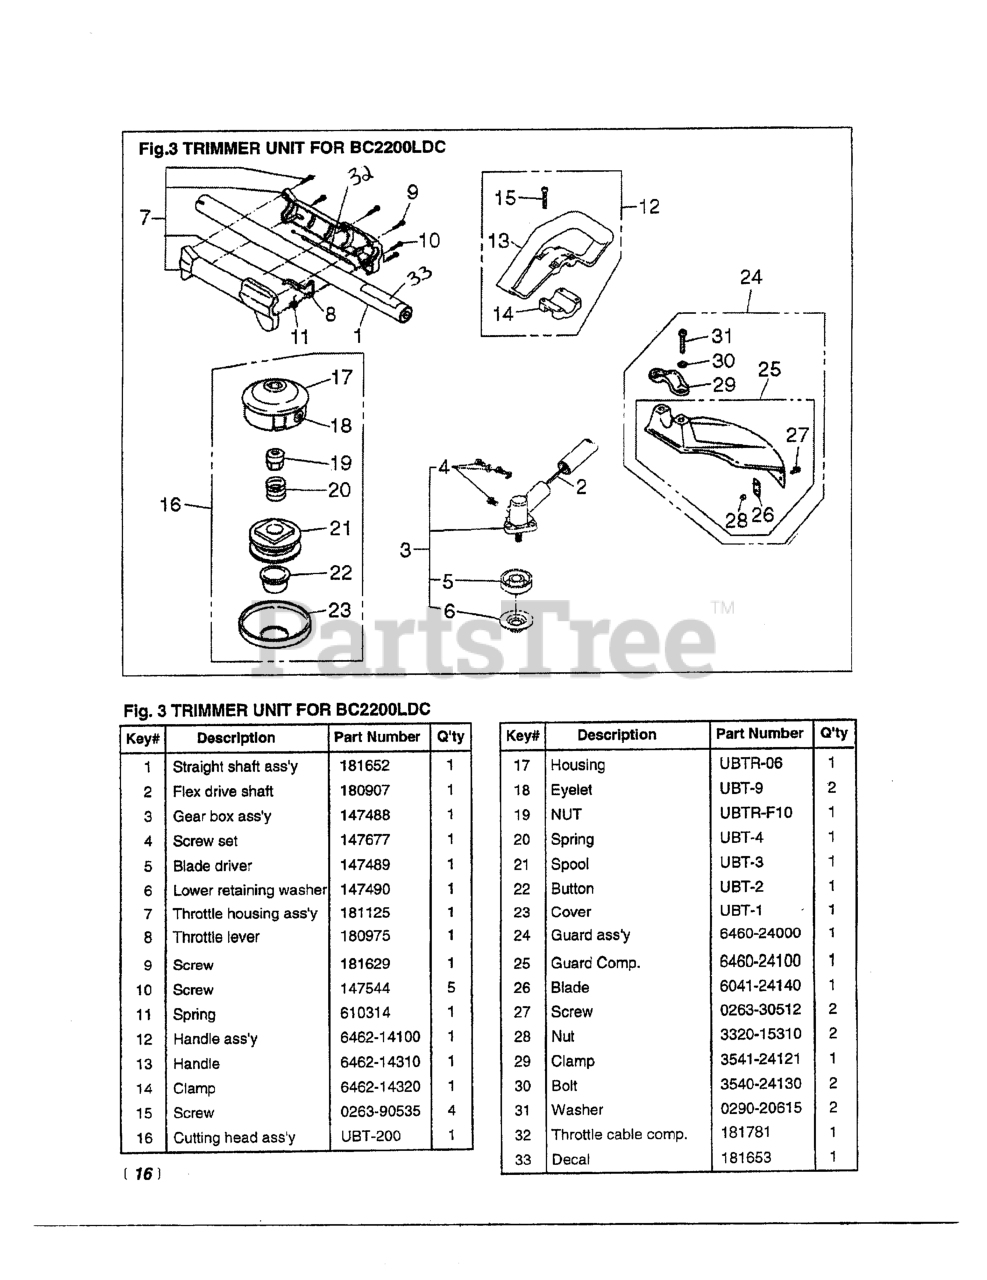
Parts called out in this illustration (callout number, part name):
1	DRIVE SHAFT HSG ASSY (SS)
2	SHAFT, FLEX (RLPS. 181773)
3	GEARCASE ASSEMBLY
4	HARDWARE, MOUNTING
5	HOLDER (U), BLADE DRIVER
6	HOLDER (L) (RPLS 613222)
8	LEVER, THROTTLE
9	SCREW, 8-32 X .437
11	SPRING, THROTTLE TRIGGER
12	HANDLE ASSEMBLY
13	HANDLE
14	CLAMP
15	SCREW, M5 x 35
16	CUTTING HEAD ASSY
17	HOUSING (ROUND) (NLA)
18	EYELET
19	BOLT (10MM ROUND FEMALE)
20	SPRING
21	SPOOL
22	BUTTON
23	COVER
24	GUARD ASSEMBLY
26	BLADE
27	SCREW, M5 x 12
28	NUT
29	CLAMP
30	BOLT, M6 x 1.30
31	WASHER, M6 X 15
32	CABLE COMP (RPLS 6460- )
33	LABEL, BC2200LDC
